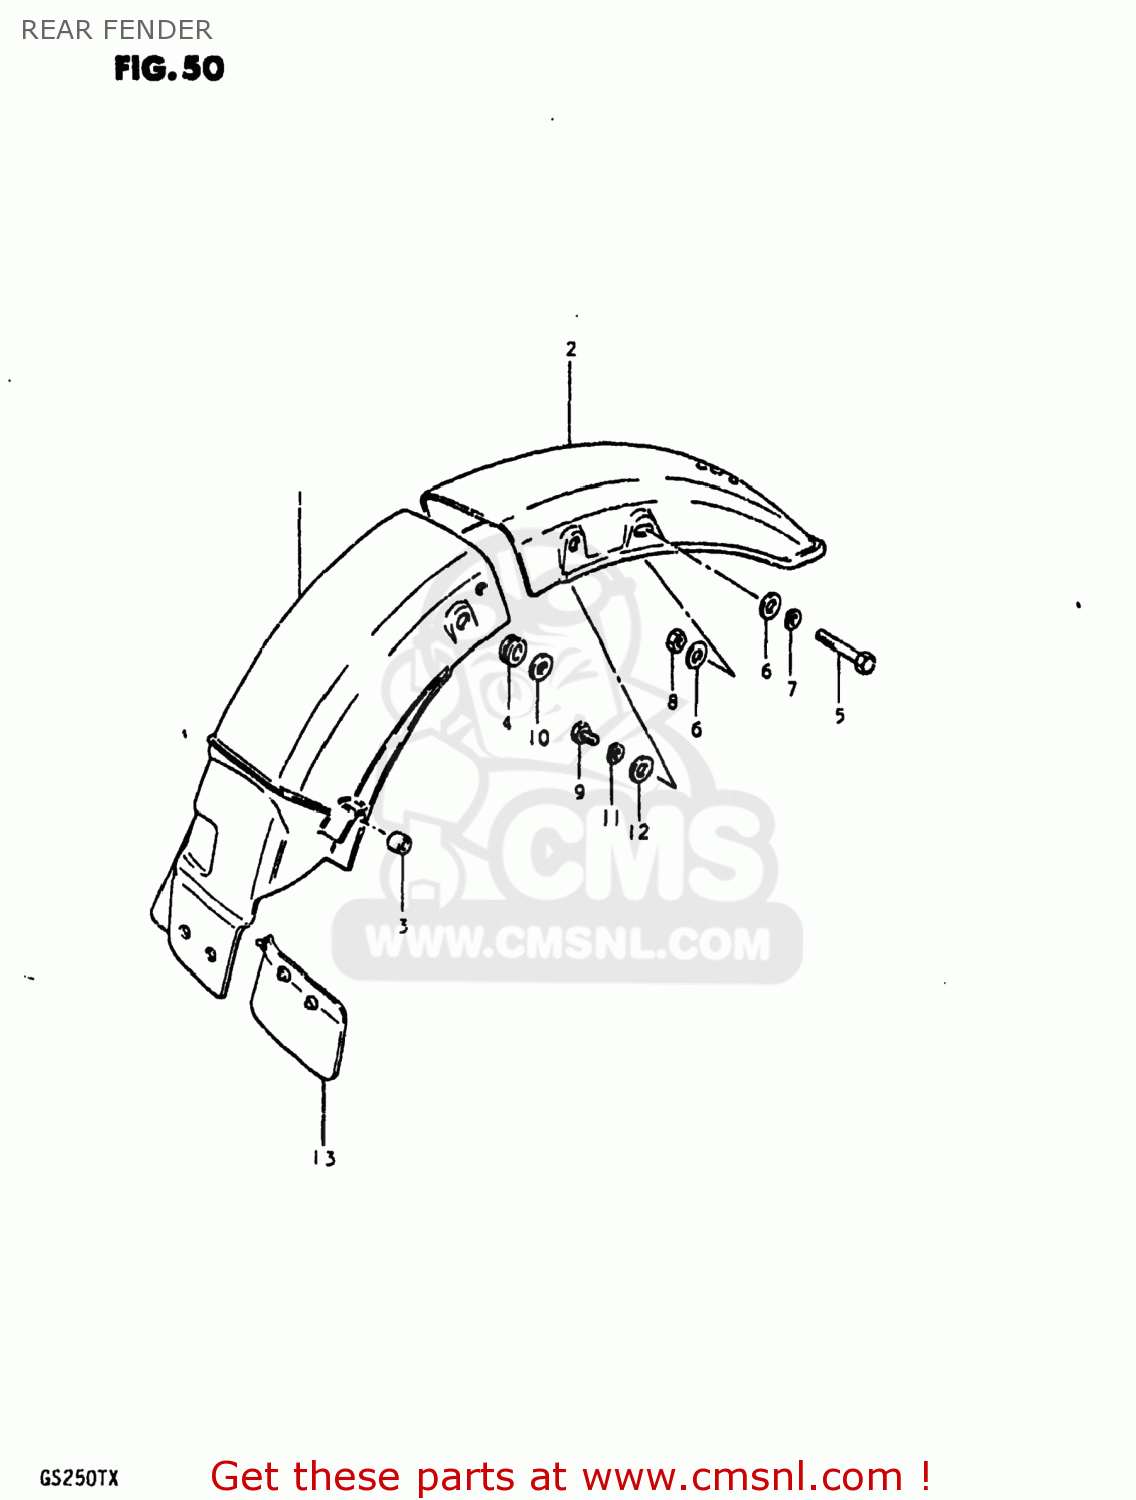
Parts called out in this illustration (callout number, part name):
1	BODY,REAR FENDER,FRONT
2	FENDER,REAR
3	CUSHION
4	CUSHION
5	BOLT
6	WASHER
7	LOCK WASHER
8	NUT
9	BOLT 8X12
10	WASHER
11	LOCK WASHER
12	WASHER
13	GUIDE,RR FENDER MUD
